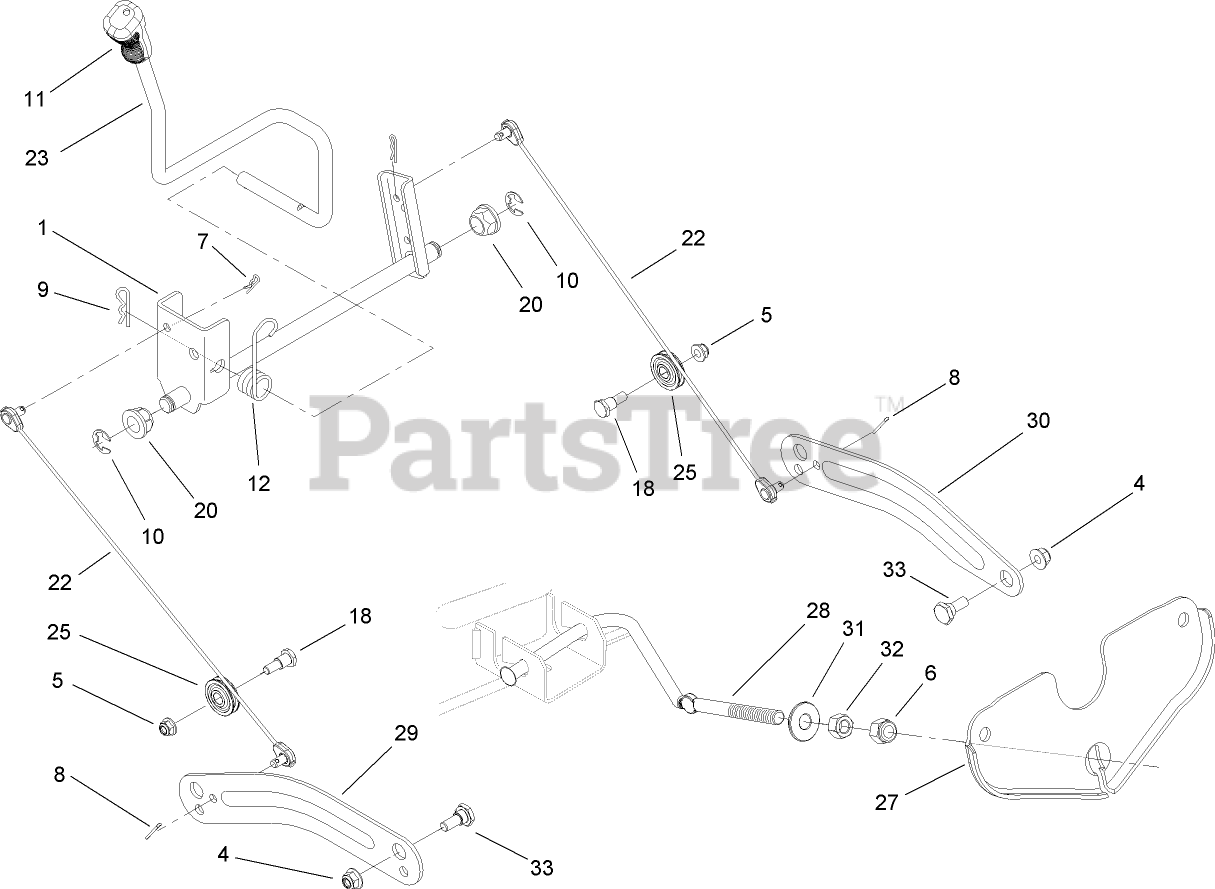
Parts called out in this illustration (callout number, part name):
1	LIFT SHAFT ASM
4	NUT-LOCK, FLANGE
5	NUT-LOCK, FLANGE
6	NUT-LOCK, HEX (NYLON)
7	PIN-COTTER
8	PIN-COTTER
9	PIN-HAIR
10	RING-E
11	GRIP-HANDLE
12	SPRING-TORSION
18	BOLT-SHOULDER
20	BEARING-FLANGE
22	CABLE-LIFT
23	HANDLE-LIFT
25	PULLEY-ROLLER
27	BRACKET-HANGER, DECK
28	ROD-DECK, FRONT ADJUSTMENT
31	CUP-PIVOT, LIFT
32	NUT-HEX
33	BOLT-SHOULDER
